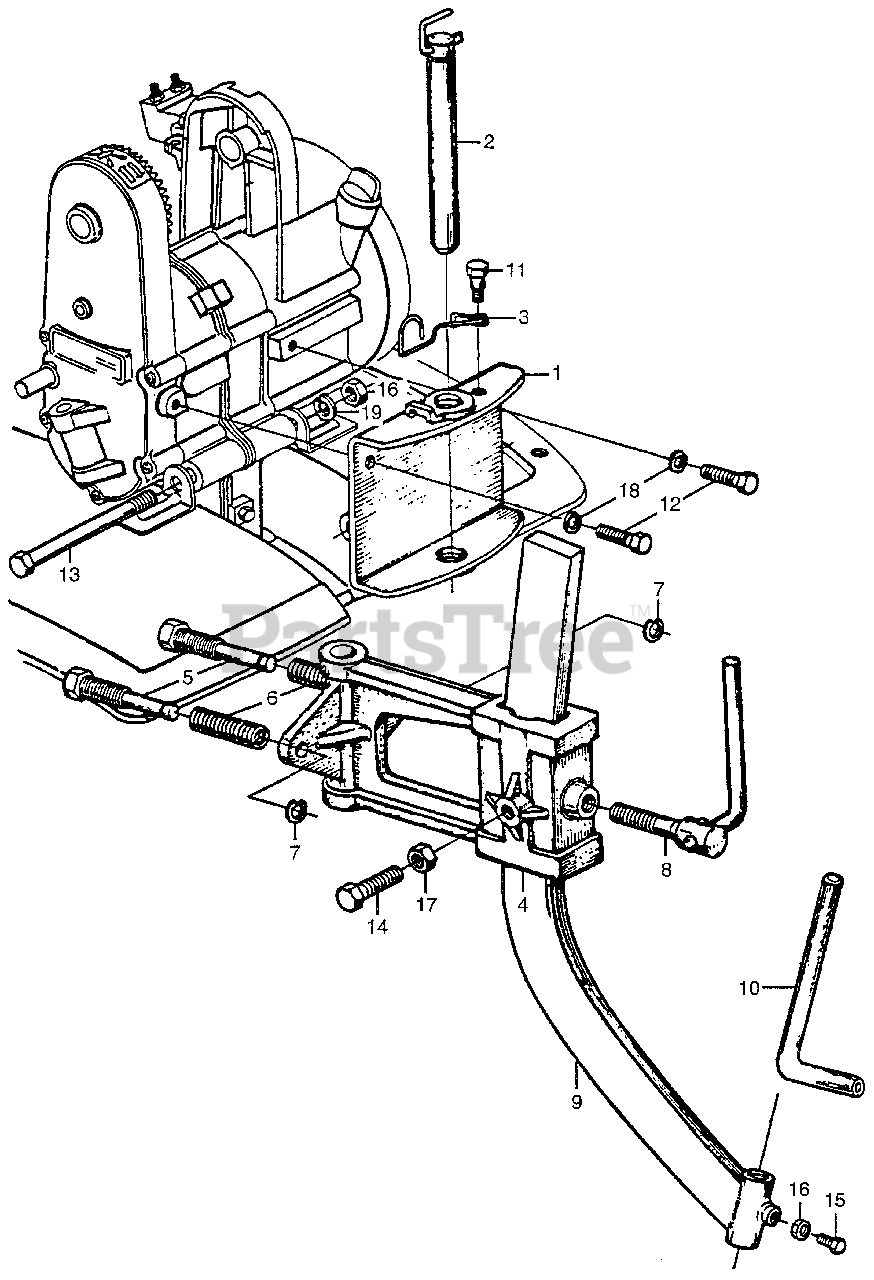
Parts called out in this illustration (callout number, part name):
1	BOX, HITCH (NOT AVAILABLE)
2	PIN, WEIGHT HOLDER
3	CLIP, HITCH PIN
4	HITCH, ATTACHMENT
5	BOLT, HITCH
6	SPRING, HITCH
8	HANDLE ASSY., STOPPER
9	BAR A, DRAG
10	BAR B, DRAG
11	BOLT, SPECIAL (6MM)
12	BOLT, HEX. (8X25)
13	BOLT, HEX. (10X80)
14	BOLT, HEX. (12X32) (NOT AVAILABLE)
15	BOLT, HEX. (10X25) (SOURCE: VINTAGE PARTS INC.)
16	NUT, HEX. (10MM)
17	NUT, HEX. (12MM)
18	WASHER, SPRING (8MM)
19	WASHER, SPRING (8MM)
